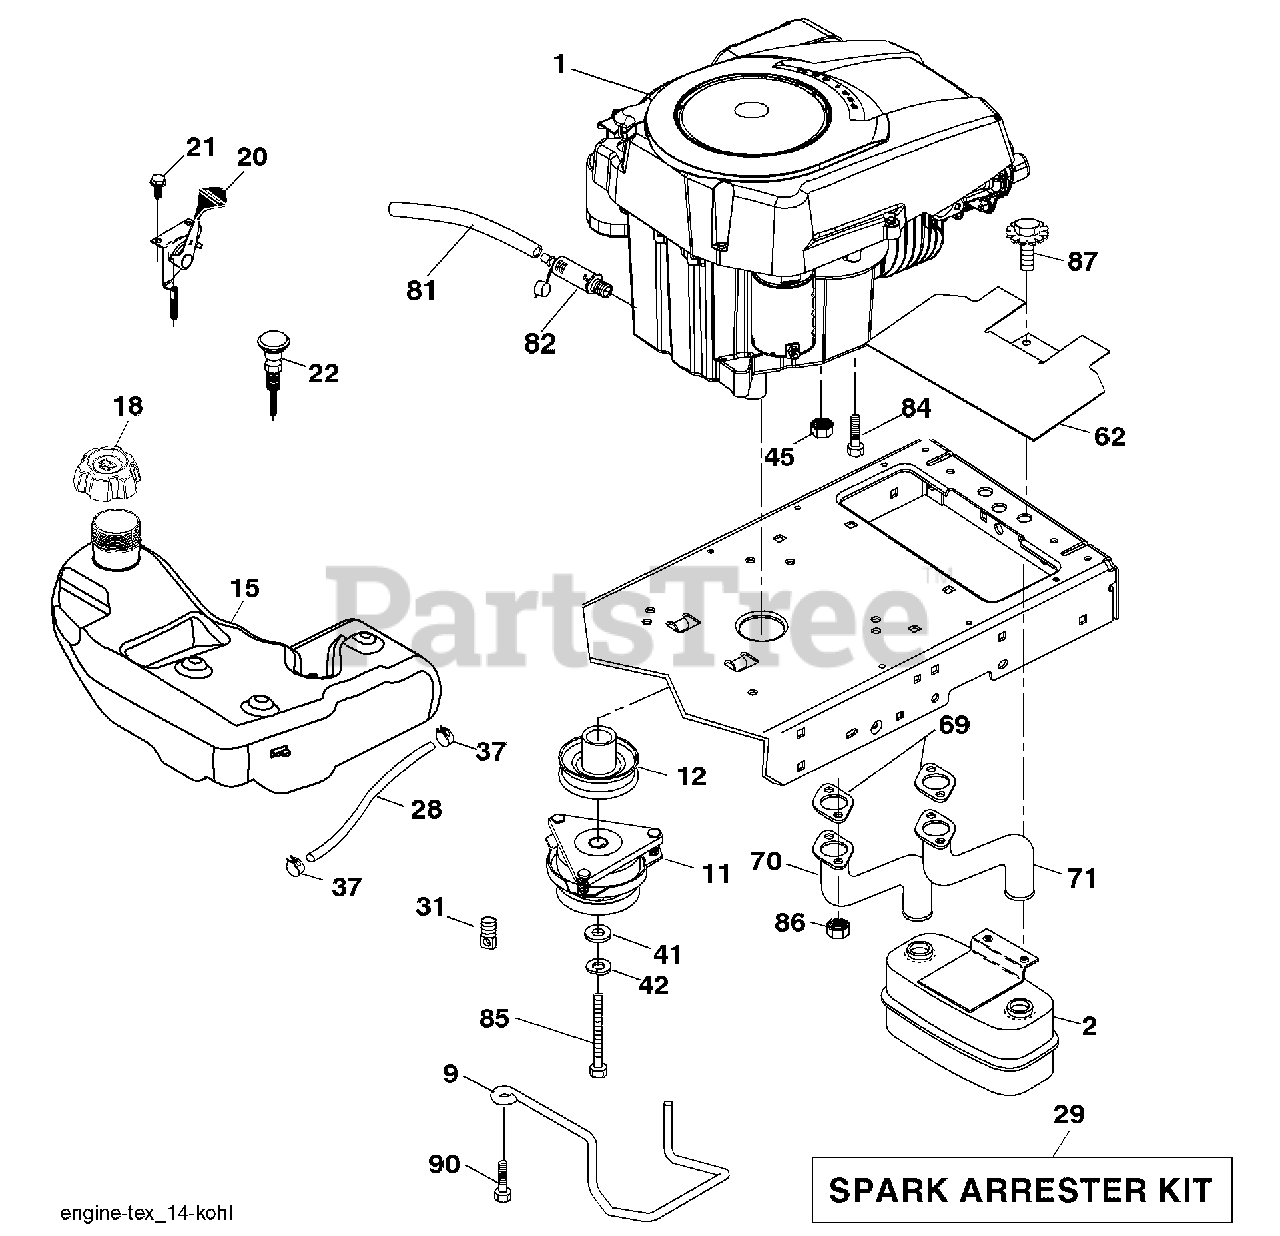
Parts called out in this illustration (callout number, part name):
9	Keeper Belt Engine
11	Clutch Electric
12	Pulley Engine
15	Tank Fuel 4.0
18	Cap Asm
20	Control Throttle
21	Screw 10 x 3/4 Single Lead Hex
22	Control Choke
28	Fuel Line
29	Spark Arrester Kit
31	Clip Push-In
37	Clamp Hose
41	Washer 1-1/2 OD x 15/32 ID x .250
42	Washer Lock 7/16
45	Nut Keps Hex 1/4-20 unc
62	Shield Heat Muffler
69	Gasket
70	Tube Exhaust LH
71	Tube Exhaust RH
81	Tube Drain Oil Easy
82	Plug Drain Oil
84	Screw 3/8-16 x 1
85	Bolt Hex 7/16-20 x 3.75 Gr. 5
86	Nut Hex Flange Toplock M8-1.25
87	Bolt 5/16-18 unc x 1 w/Sems
90	Screw 3/8-16 x 1
